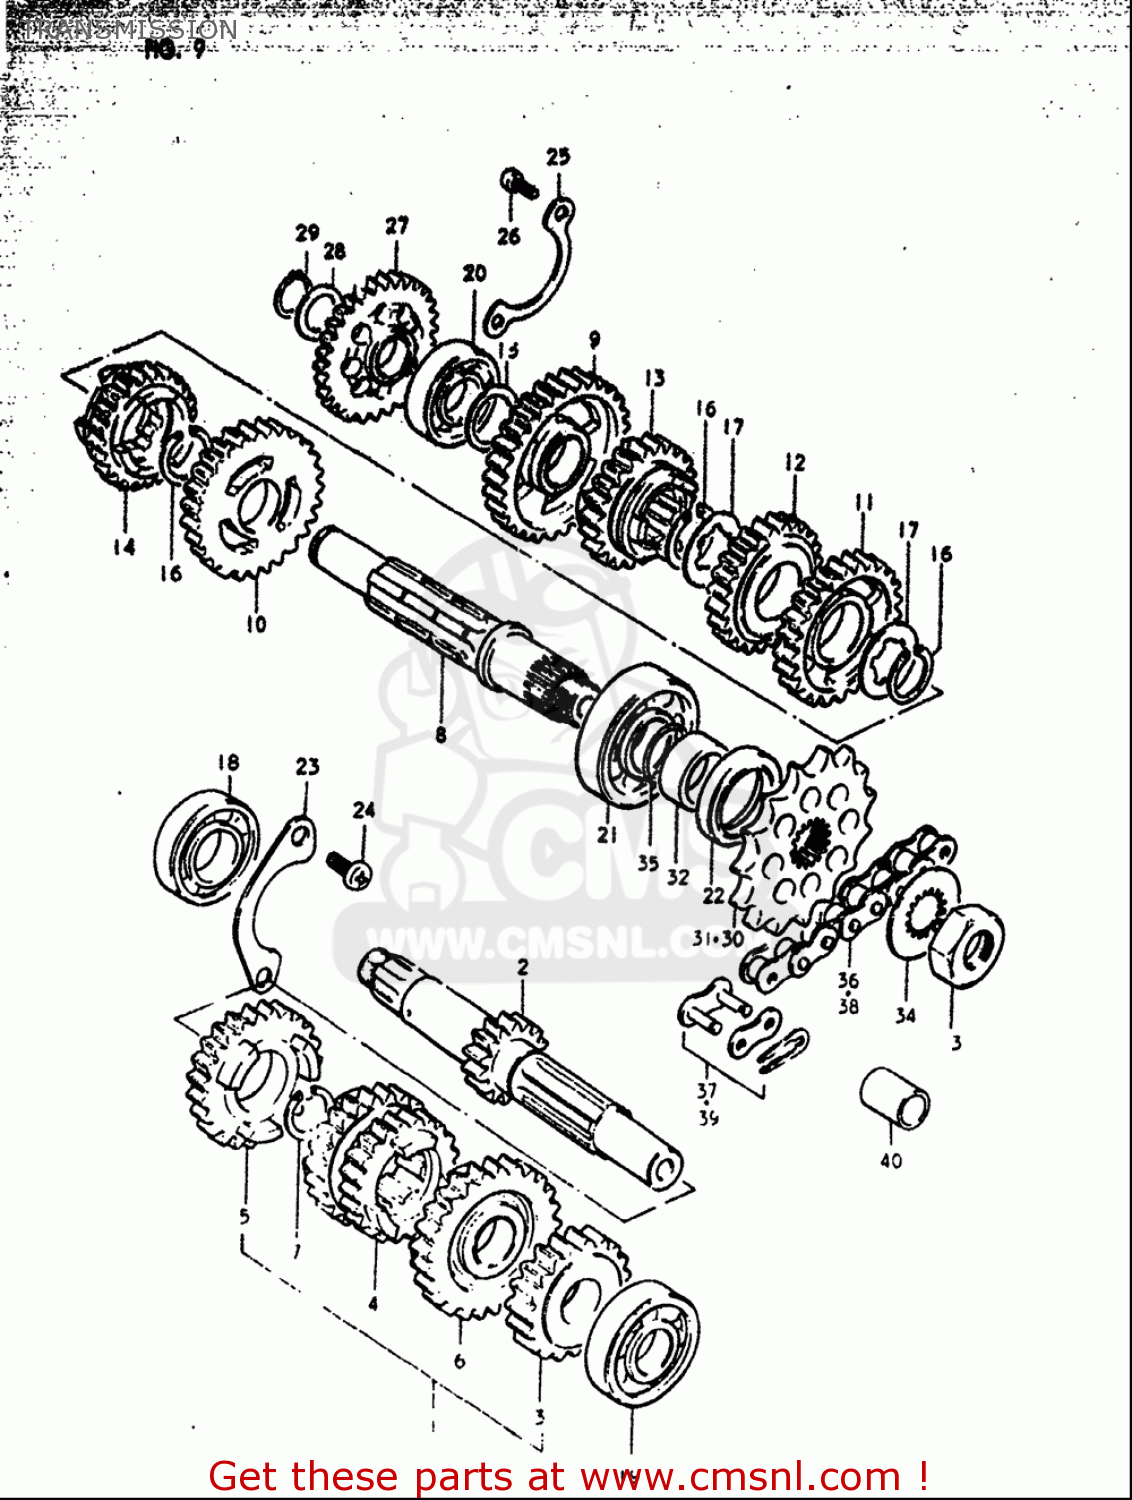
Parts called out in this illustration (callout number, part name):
2	SHAFT,COUNTER
3	GEAR,2ND DRIVE
4	GEAR,THIRD/FOURTH DRIVE
5	GEAR,FIFTH DRIVE
7	CIRCLIP
12	GEAR,FOURTH DRIVEN
13	GEAR,FIFTH DRIVEN
15	SHIM, 15X24X1.0
16	CIRCLIP
17	WASHER,LOCK
18	BEARING(20X47X14)
19	BEARING
20	BEARING
21	BEARING(20X47X14)
22	SEAL,OIL(25X40X7)
23	RETAINER,CNTR SHAFT BEARING
24	SCREW
26	SCREW
27	GEAR,KICK STARTER IDLE
28	SHIM, 15X24X1.0
29	CIRCLIP
30	SPROCKET,ENGINE
31	SPROCKET,ENGINE
32	SPACER(20X25X12.5)
33	NUT
34	WASHER,LOCK
35	O RING(D:1,ID:19.5)
38	CHAIN ASSEMBLY,DRIVE
39	JOINT,CHAIN
40	CUSHION
